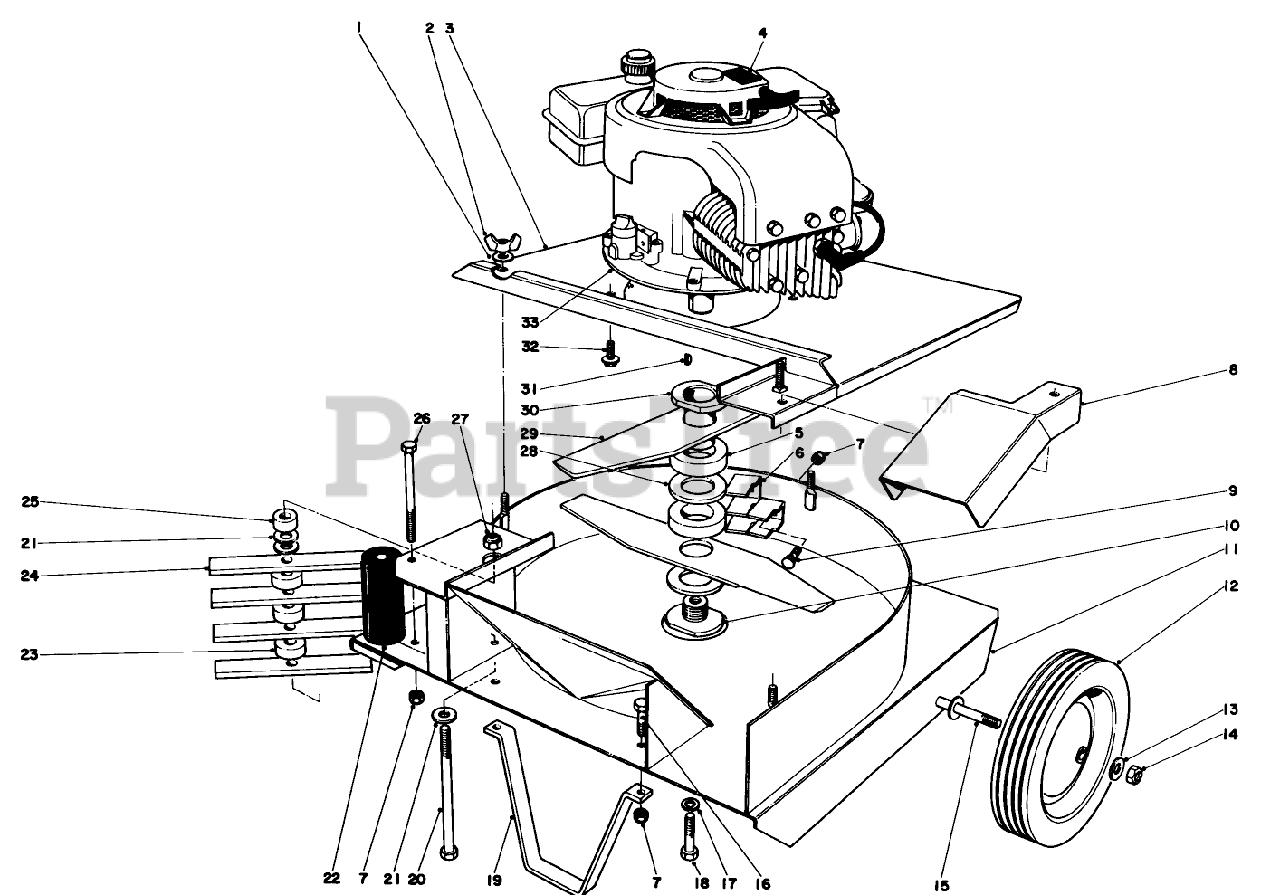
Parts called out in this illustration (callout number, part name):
1	WASHER-FLAT
2	NUT-WING
3	Engine Base W.A.
4	Caution Decal
5	Hub Spacer
6	Secondary Finger
7	NUT-LOCK, CONE
8	Deflector
9	BOLT-CARR
10	Hub Keeper
12	Wheel
13	WASHER-FLAT
14	1/2-13 CONELOCK NUT
16	SCREW-HH
17	WASHER-LOCK/SP
18	Capscrew
19	Leg Stand
20	Special Screw
21	WASHER-FLAT
22	Shock Absorber
23	Lower Finger Spacer
24	Primary Finger
25	SPACER-FINGER
26	SCREW-HH
27	NUT-LOCK, NI
28	Blade Spacer
29	Blade
31	KEY-WOODRUFF
32	SCREW-HWHTF
33	Engine
